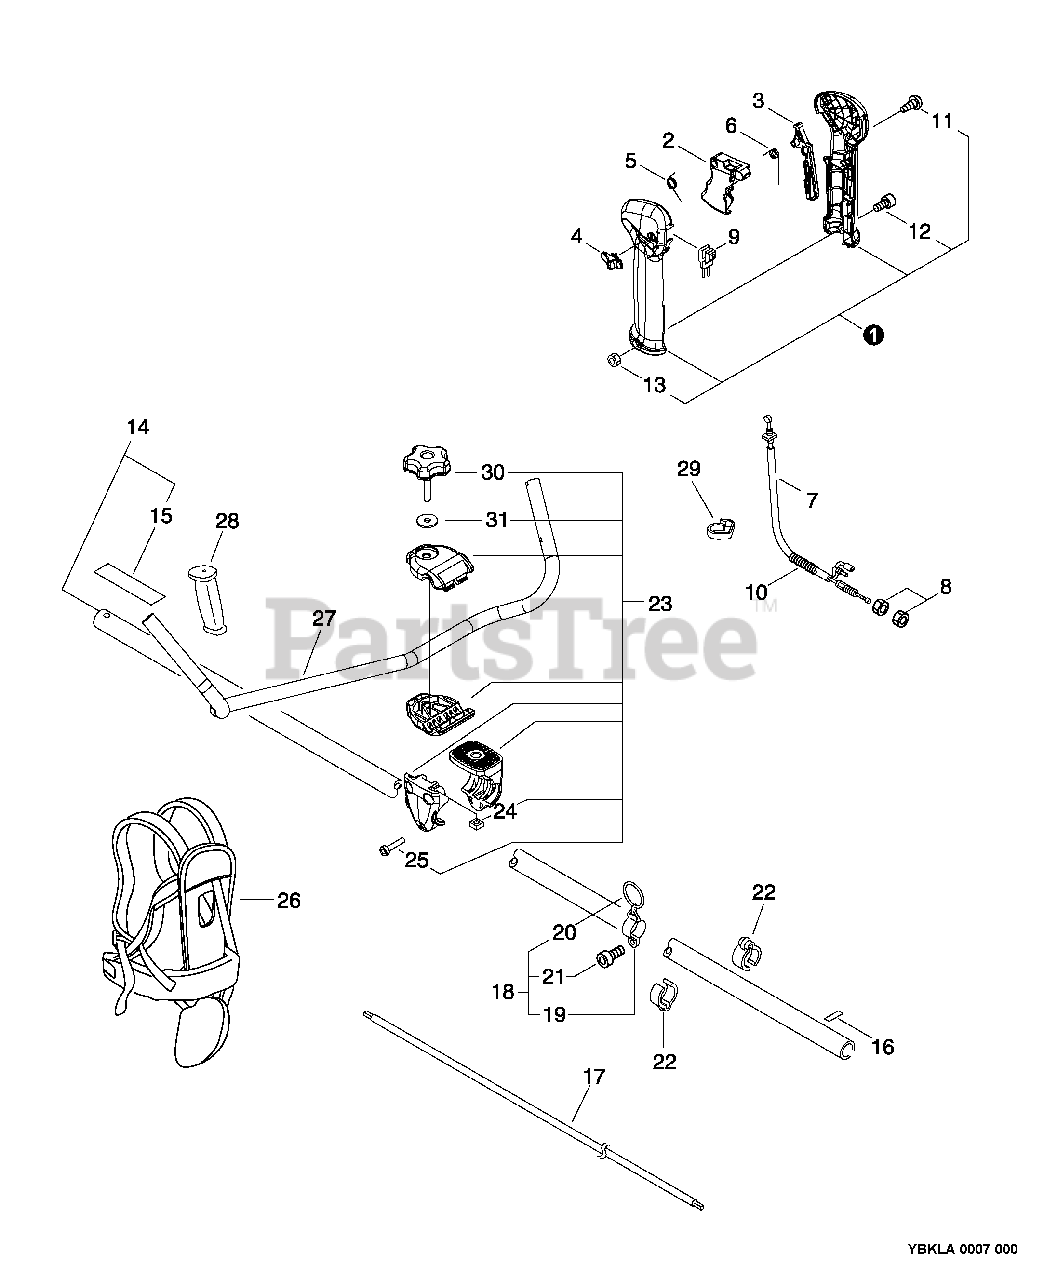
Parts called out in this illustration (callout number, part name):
1	CONTROL HANDLE ASSY
2	TRIGGER, THROTTLE
3	LEVER, TRIGGER LOCKOUT
4	LOCK, THROTTLE
5	SPRING, TRIGGER
6	SPRING, LOCKOUT LEVER
7	CABLE, THROTTLE
9	IGNITION SWITCH ASSY
11	SCREW - 4X16
12	SCREW - 5X30
14	MAIN PIPE ASSY
15	LABEL - CAUTION
16	LABEL - ALIGNMENT
17	DRIVESHAFT - SOLID
18	HANGER ASSY
19	CLAMP
21	SCREW - 5X12
23	HANDLE BRACKET KIT
25	SCREW - 5X30
26	HARNESS ASSY
27	HANDLE - FRONT
28	GRIP, HANDLE
30	THUMBSCREW
31	WASHER - 8
